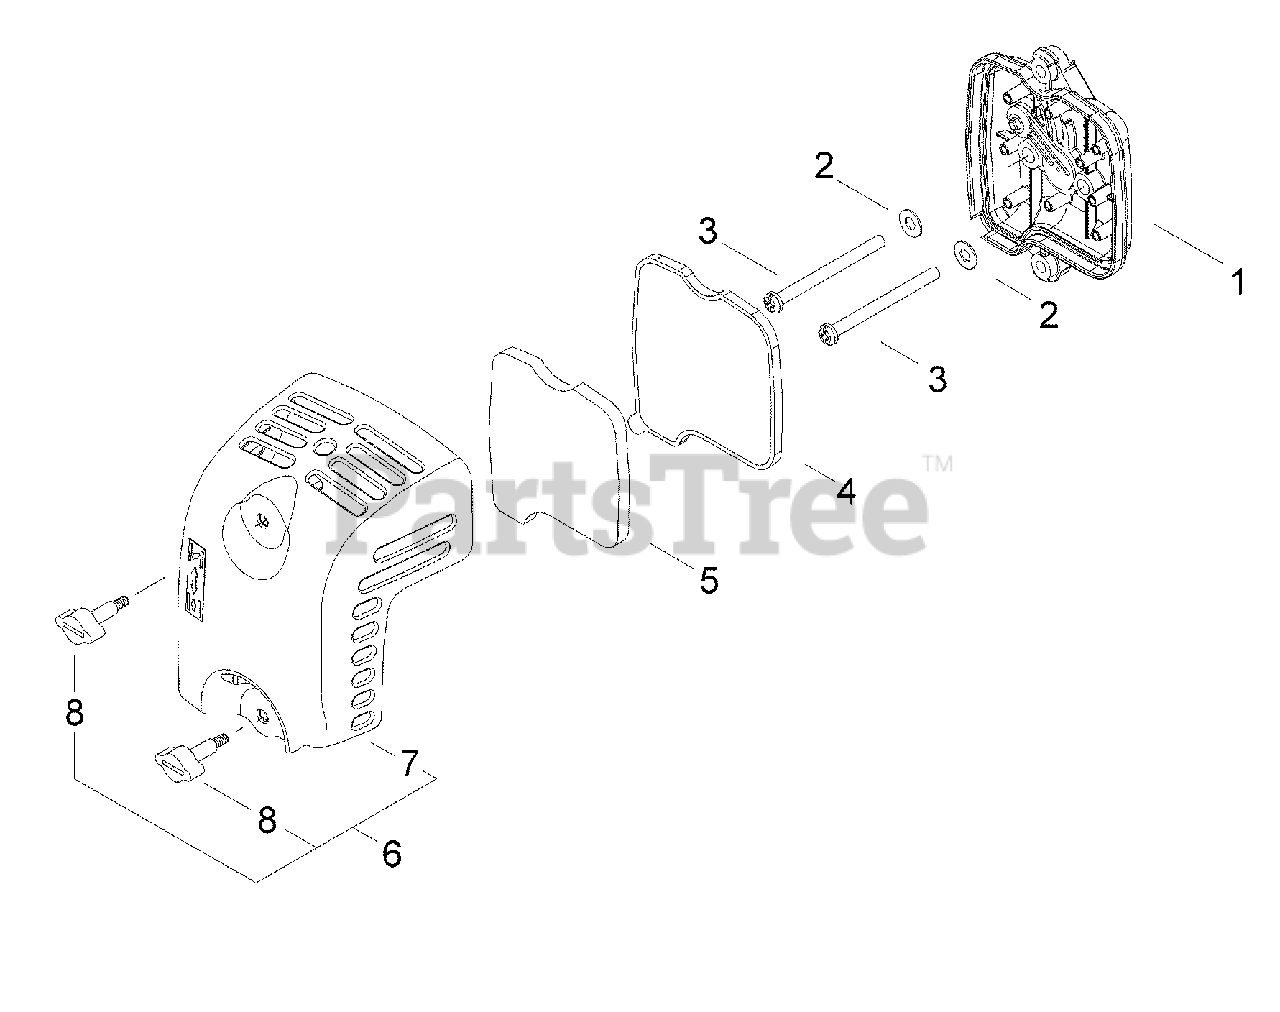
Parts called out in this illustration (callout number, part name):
1	CASE ASSY, AIR FILTER
2	WASHER 5 MM
3	SCREW M5×60
4	FILTER, AIR
5	PRE-FILTER, FOAM
6	COVER ASSY, AIR FILTER
7	COVER, AIR FILTER
8	THUMBSCREW M5
